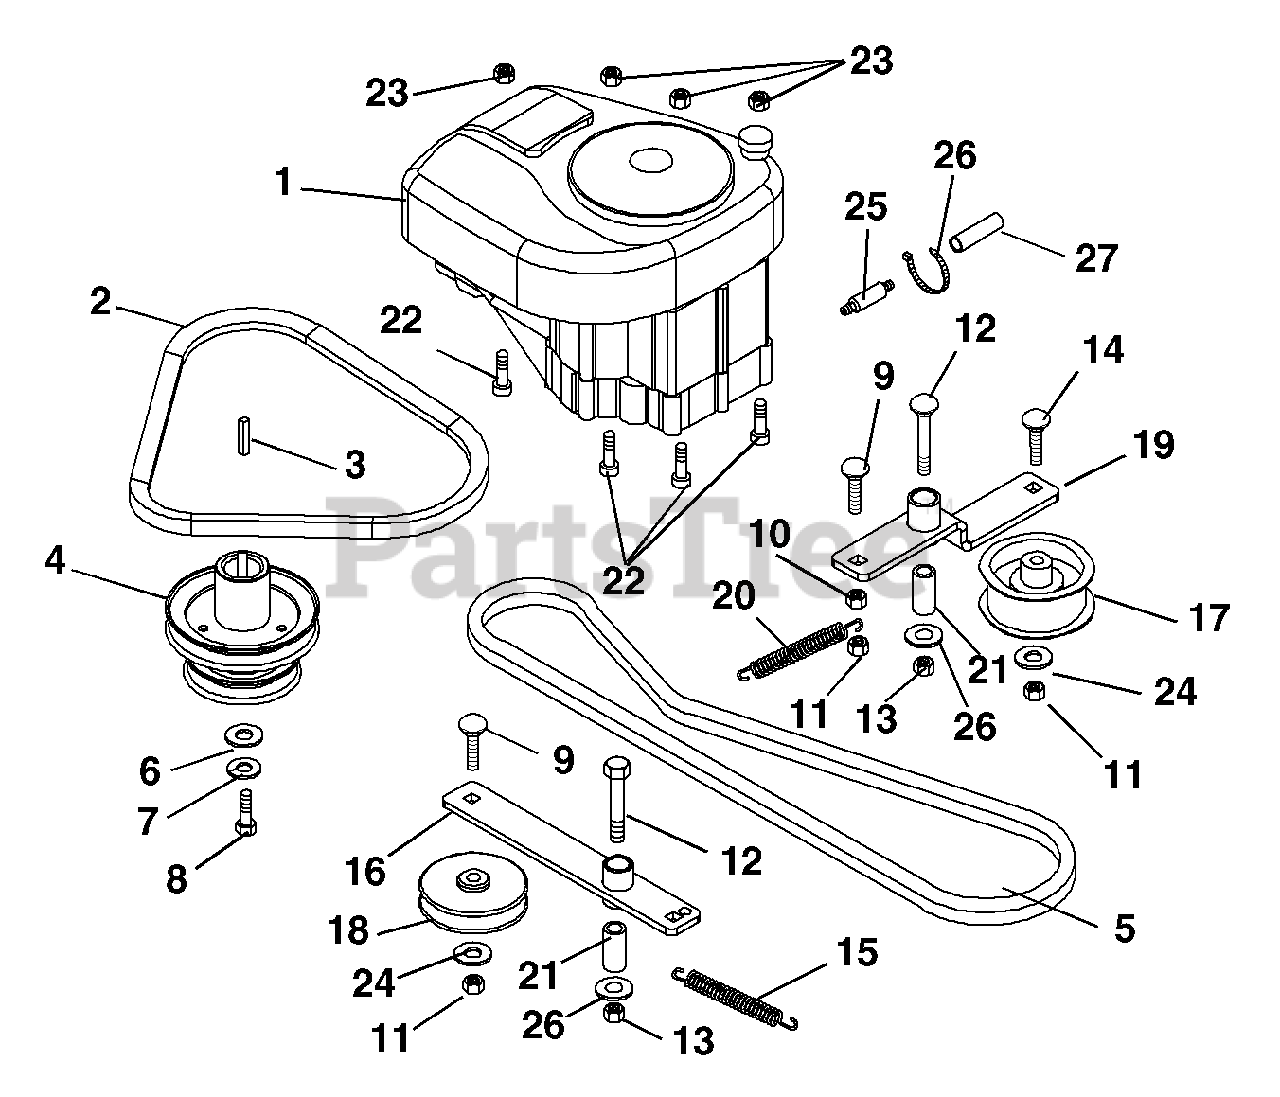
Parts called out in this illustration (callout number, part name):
1	GROUP-ENG 12HP INTEK AVS
1	ENG GROUP 10HP INTEK AVS
1	GROUP-ENG 14HP INTEK AVS
2	V-BELT, 4L-RAW EDGE
3	KEY-STR .25X1.75X.25
4	STACK, RER ENGINE SHEAVE
4	STACK, RER 40" DECK SHEAVE
5	V-BELT, HA-WRAPPED
6	WSHR-FL-STL.463X1.375X.25 YWZC
7	@WSHR-LK .44X.109 REG YWZC
8	BLT-HEX .44-20X1.75 GR5 YWZC
9	@BLT-RDHDSQNK .38-16X1.25 G5YZ
10	@NUT-SPNLK-FLG .375-16 YWZC
11	NUT-LK-TOP-FLG .38-16 BLKZC
12	@BLT-HEX .50-13X2.25 GR5 YWZC
13	NUT-LK ESNA THIN .50-13 YWZC
14	@BLT-RDHDSQNK .38-16X2.00 G5YZ
15	SG-TENS .095X.500X5.5 WLD60 YZ
16	IDLER, DRIVE (WLDMNT)
17	IDLER 2.75X1.25
18	IDLER-V 3X.38
19	IDLER, RER PTO (WLDMNT)
19	IDLER, 40" DECK PTO
20	SG-TENS .093X.75X4.0 WLD40
21	BSHG-SLV .500X.750X1.560
22	SCR-SKH BTHD .31-18 X 1.50 GR8
23	NUT-LK-TOP-FLG .31-18 BLKZC
24	@WSHR-FL-STL.38X.875X.083 YWZC
25	VALVE, OIL DRAIN
26	CABLE TIE LG 5-1/2
27	TUBE, OIL DRAIN 8" CLEAR VINYL
28	@WSHR-FL-STL.563X1.38X.109YWZC
